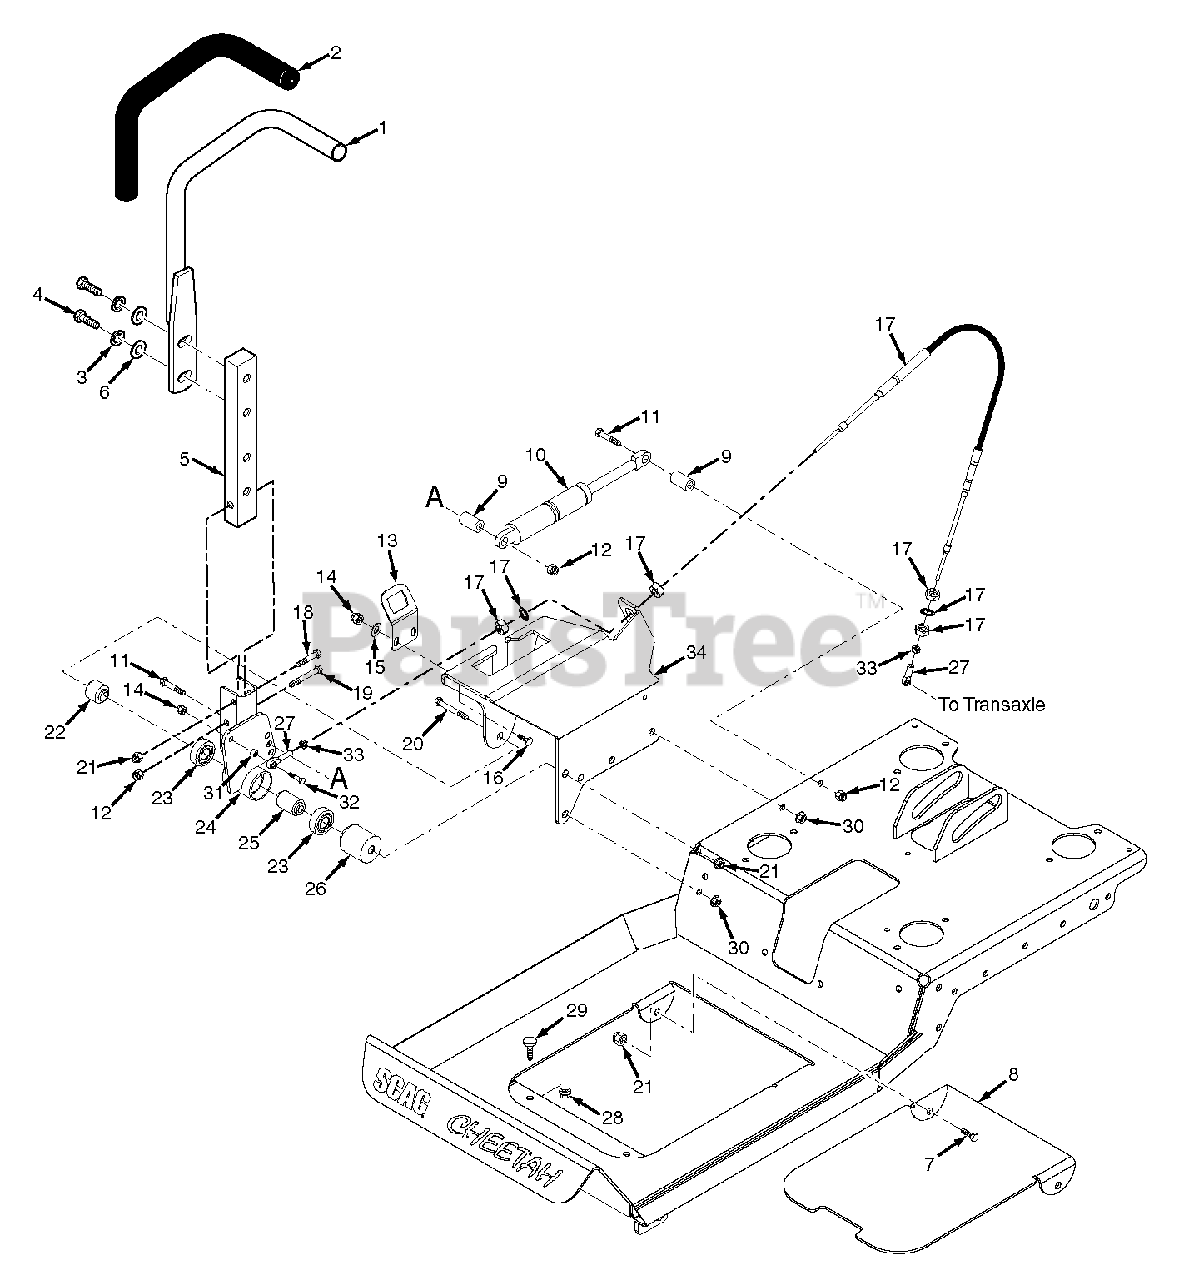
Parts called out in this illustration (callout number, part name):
1	Handle Bar w/Grip
2	Grip, Control Handle
3	Lockwasher, 3/8" Spring
4	Bolt, Hex Head 3/8-16 x 1-1/4'
5	Bar, Control Lever
6	Flatwasher, 3/8-.391 x .938 x .105
7	Bolt, Hex Head 3/8-16 x 1"
8	Cover, Foot Plate
9	Spacer
10	Damper
11	Bolt, Hex Head 5/16-18 x 2"
12	Nut, Elastic Stop 5/16-18
13	Bracket, Operator Presence Switch
14	Nut, Elastic Stop 1/4-20
15	Flatwasher, 1/4-.312 x .750 x .065
16	Bolt, Carriage 1/4-20 x 3/4"
17	Control Cable, Hydro
18	Bolt, Hex Head 3/8-16 x 2"
19	Bolt, Hex Head 5/16-18 x 2"
20	Bolt, Hex Head 3/8-16 x 6"
21	Nut, Elastic Stop 3/8-16
22	Spacer, Controls
23	Bearing
24	Pivot Weldment, Control Arm LH
24	Pivot Weldment, Control Arm RH
25	Spacer, Bearing
26	Spacer, Controls
27	Rod End, 1/4-28 RH Thread
28	Nut, Serrated Flange 5/16-18
29	Bumper, Rubber
30	Nut, Serrated Flange 3/8-16
31	Spacer
32	Bolt, Hex Head 1/4-20 x 1-1/4"
33	Nut, Jam 1/4-28 UNF
34	Bracket Weldment, Control Lever RH w/Decal
34	Bracket Weldment, Control Lever LH w/Decal
